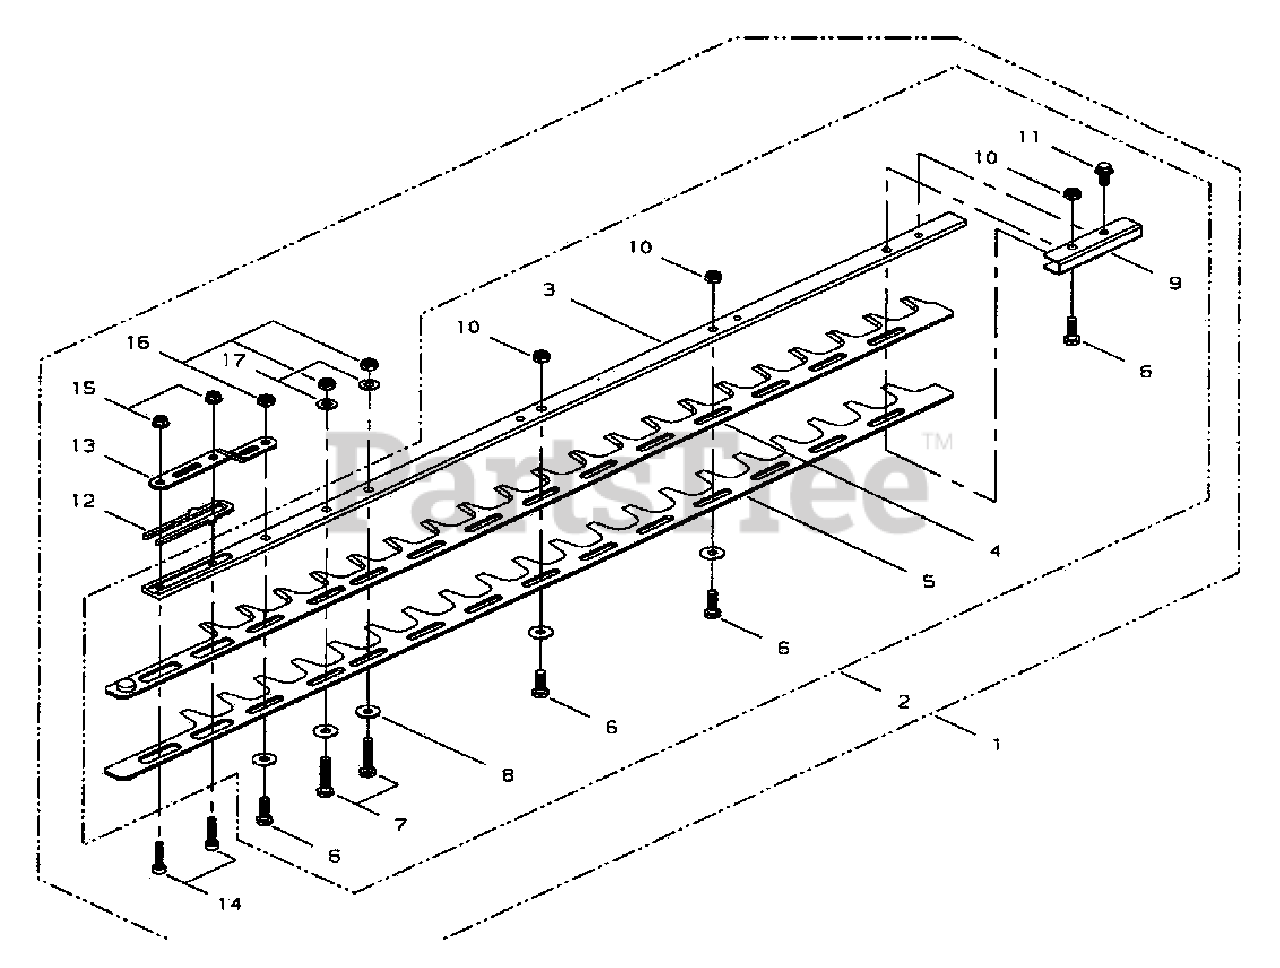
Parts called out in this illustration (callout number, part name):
1	BLADE KIT - 30" (76cm)
2	BLADE KIT - 30" (76cm) HD
3	SUPPORT, BLADE - 30" (76cm)
4	BLADE - 30" HD -- UPPER
5	BLADE - 30" (76cm) HD - LOWER
6	BOLT - 6X20
7	BOLT - 6X32
8	WASHER - 6
9	PLATE, GUIDE
10	NUT - 6
11	BOLT - 5X8
14	SCREW - 5X25
15	NUT - 5
16	NUT - 6
17	WASHER - 6
